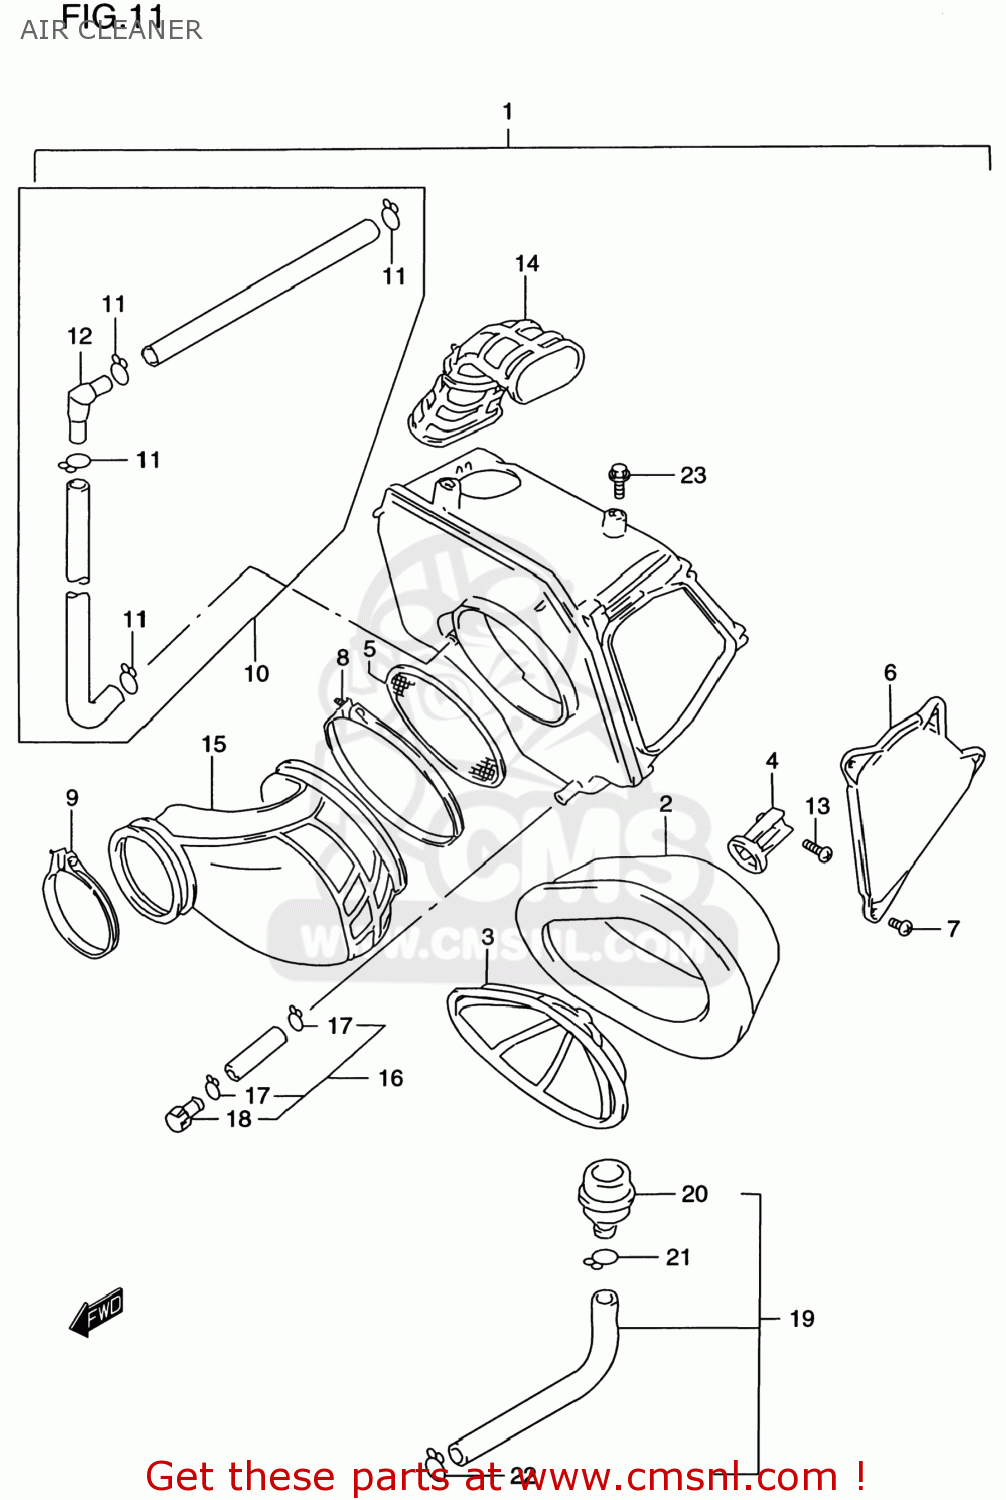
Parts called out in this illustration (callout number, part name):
1	CLEANER ASSY,AIR
2	FILTER
3	HOLDER,FILTER
4	STOPPER,HOLDER
5	TRAP,FRAME
6	CAP,CLEANER
7	SCREW 5X12
8	CLAMP,OUTLET TUBE
9	CLAMP
10	TUBE ASSY,BREATHER
11	CLIP
12	JOINT
13	SCREW
14	TUBE,INLET
15	TUBE,OUTLET
16	TUBE ASSY,DRAIN
17	CLIP
18	PLUG
19	CLEANER ASSY,AIR NO.2
20	FILTER,2ND AIR CLEANER
21	CLIP
22	CLIP
23	BOLT
